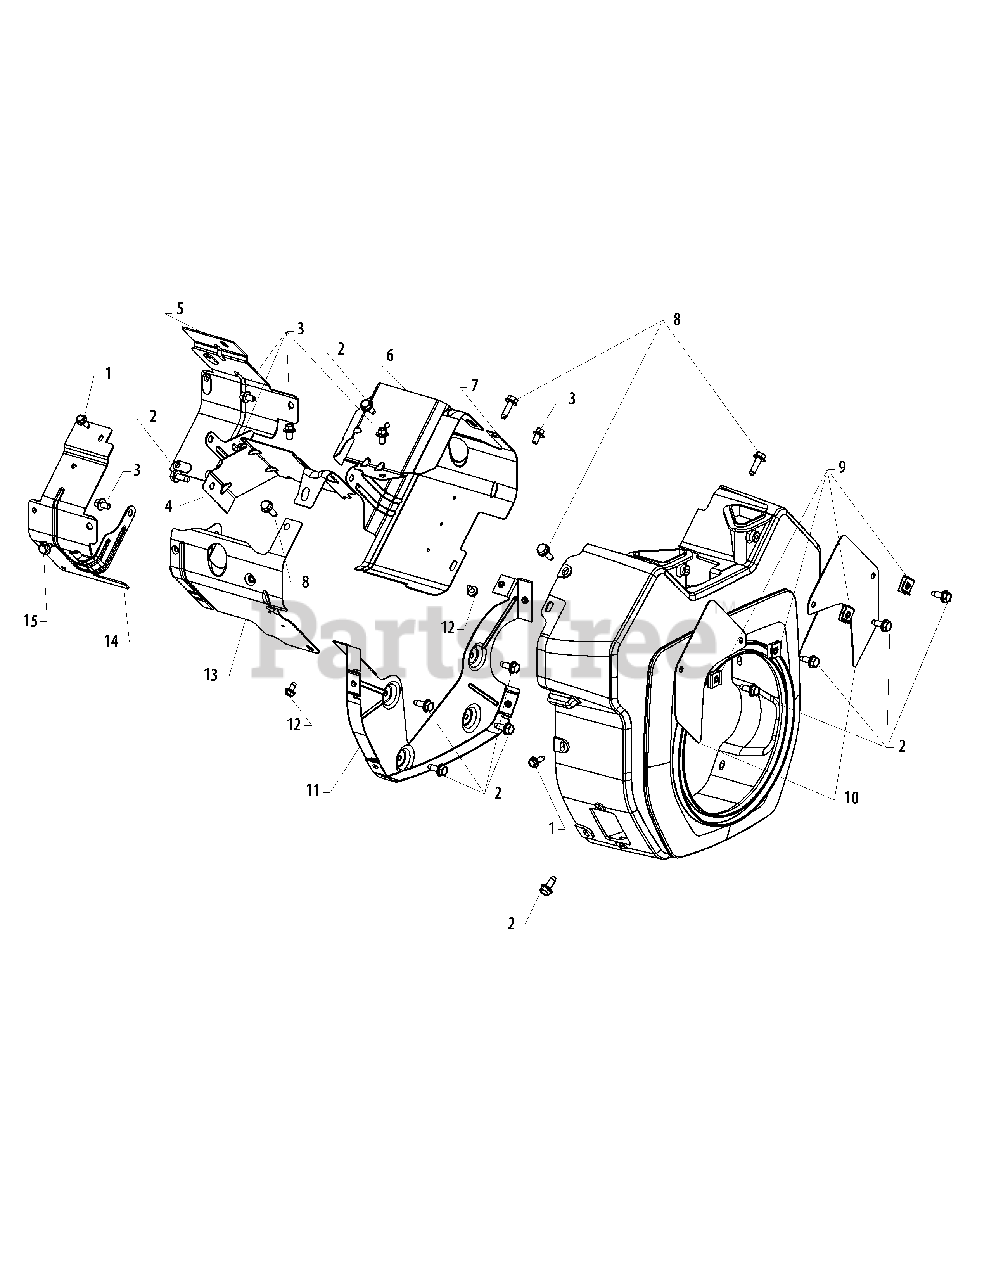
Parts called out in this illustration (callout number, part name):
1	Screw, Flg Thd Frm M5x0.8x16
2	Screw, Flg Thd Frm M6x1.0x16
3	Screw, Flg M6x1.0x10
4	Baffle, Valley #2 Cylinder
5	Baffle, Ducted Air-Starter
6	Baffle, Valley #1 Cylinder
7	Kit, Cyl Barrel - #1 Side
8	Screw, Flg Thd Frm M6x1.0x20
9	Clip, Baffle Mounting
10	Kit, Access Panel
11	Kit, Backing Plate
12	Screw, Flg Thd Frm M5x0.8x10
13	Kit, Cyl Baffle - #2 Side
14	Baffle, Ducted Air-Oil Filter
15	Screw, Flg Thd Frm M6x1.0x10
